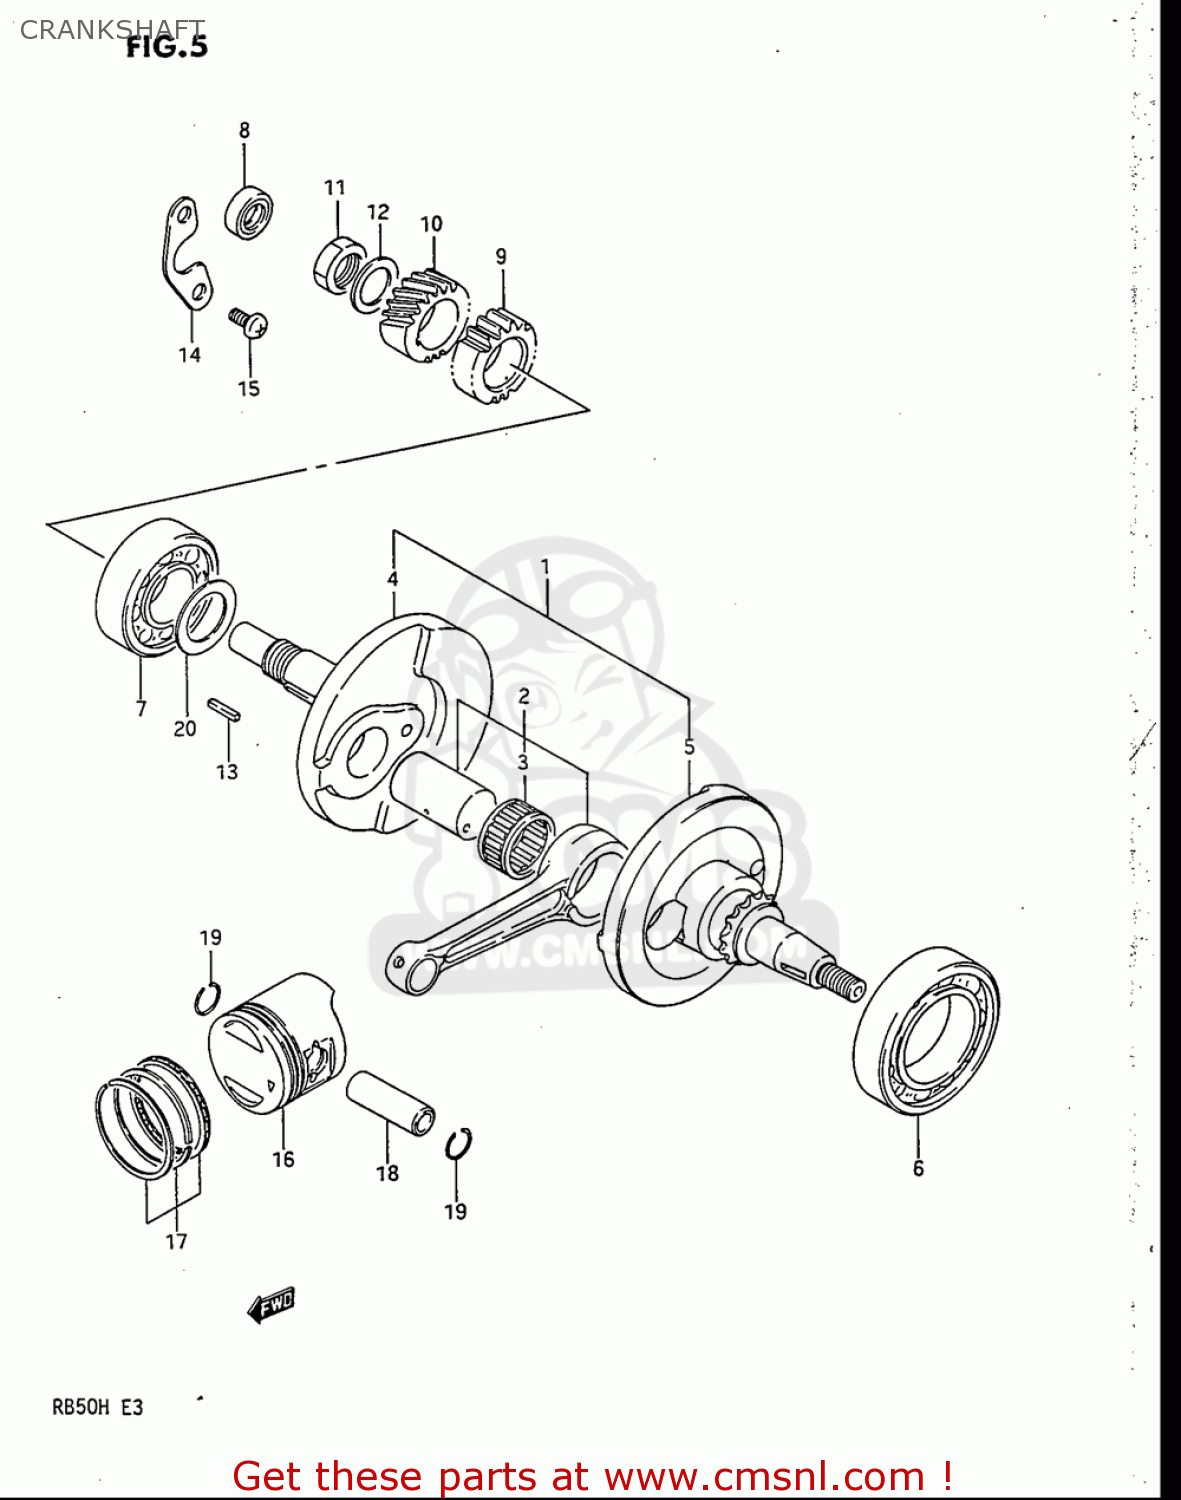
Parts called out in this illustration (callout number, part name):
2	CRANKSHAFT ASSEMBLY
3	BEARING 22.7X27.8X14
6	BEARING(35X62X14)
7	BEARING(20X52X15)
8	SEAL,OIL(12X21X7)
11	NUT
12	WASHER
15	SCREW
16	PISTON
17	RING SET,PISTON
18	PIN,PISTON
19	RING,SNAP
20	SHIM(20X30X1)
